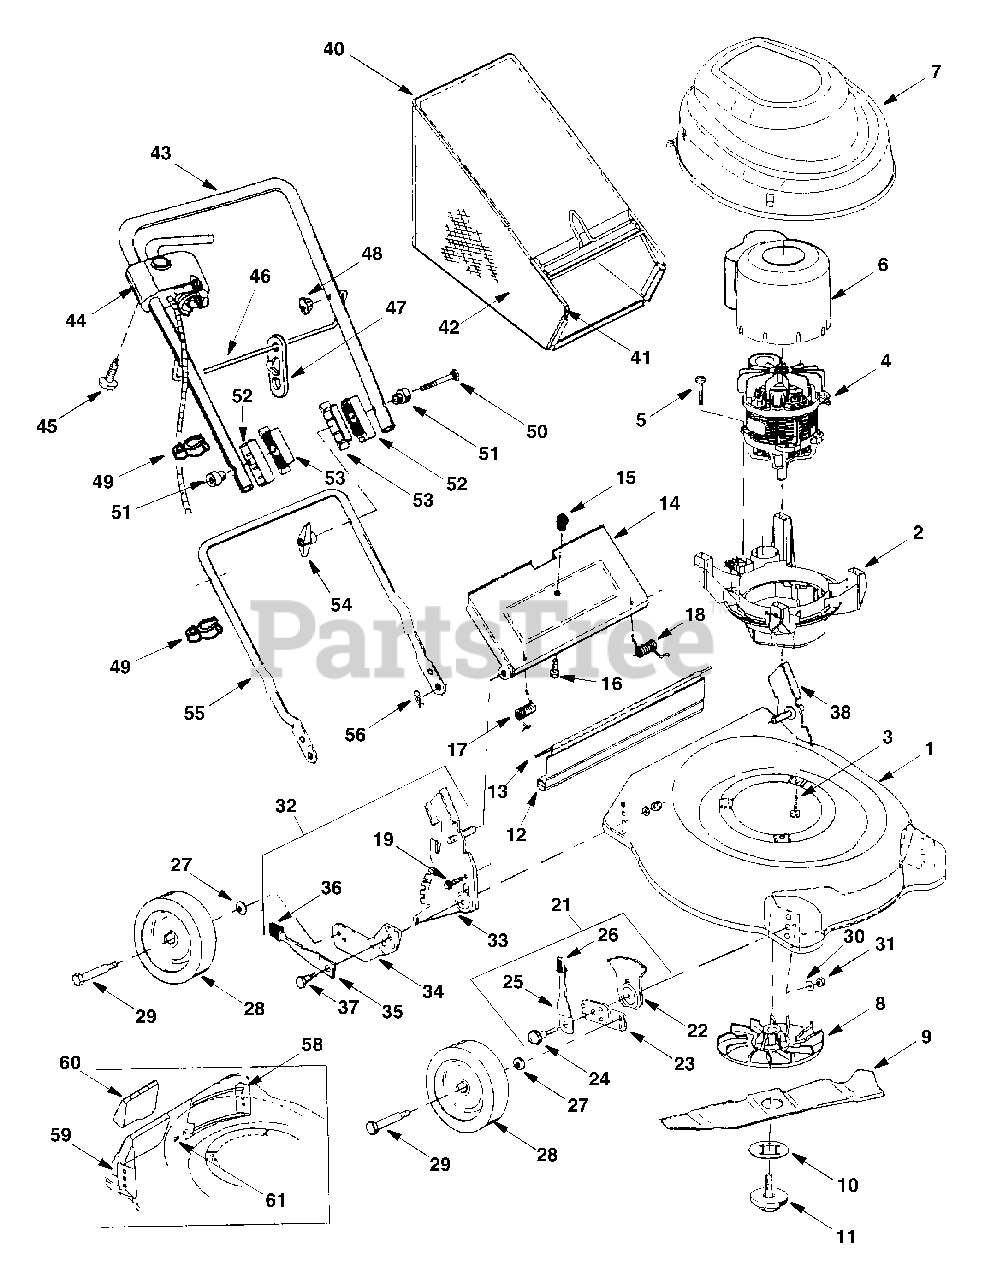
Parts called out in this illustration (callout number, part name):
3	Screw
4	Electric Motor, 115V, 1500W
5	Screw
6	Air Guide Cover
8	Blade Hub Assembly
9	Cutting Blade
10	Locking Plate
11	Screw, Blade
12	Trailing Shield
13	Wire Rod
14	Rear Discharge Door
16	Truss Screw, 10-24 x .38"
17	Door Spring, RH
18	Door Spring, LH
19	Washer Hd Screw, 1/4-14 x .625
21	Height Adj. Assy. RH
22	Adjusting Plate
24	Shoulder Bolt
25	Lever and Knob Assy.
26	Knob, Height Adjustment
27	Spring Washer
28	Wheel
29	Axle Bolt
30	Spring Washer
34	Pivot Bar, RH
35	Spring Lever
36	Spring Lever Knob
37	Shoulder Bolt
38	Handle Bracket, LH
43	Upper Handle
44	Cord and Switch Assembly
45	Screw
46	Guide Rod
48	Wing Nut
49	Cable Guide
50	Carriage Bolt
51	Insulating Washer
52	Height Adjuster, Upper Handle
53	Height Adjuster, Lower Handle
54	Handle Knob
55	Lower Handle
56	Internal Cotter Pin
58	Rear Baffle
59	Rear Mulch Baffle
60	Rear Mulch Plug
61	Tap Screw, 1/4-14 x .625"
